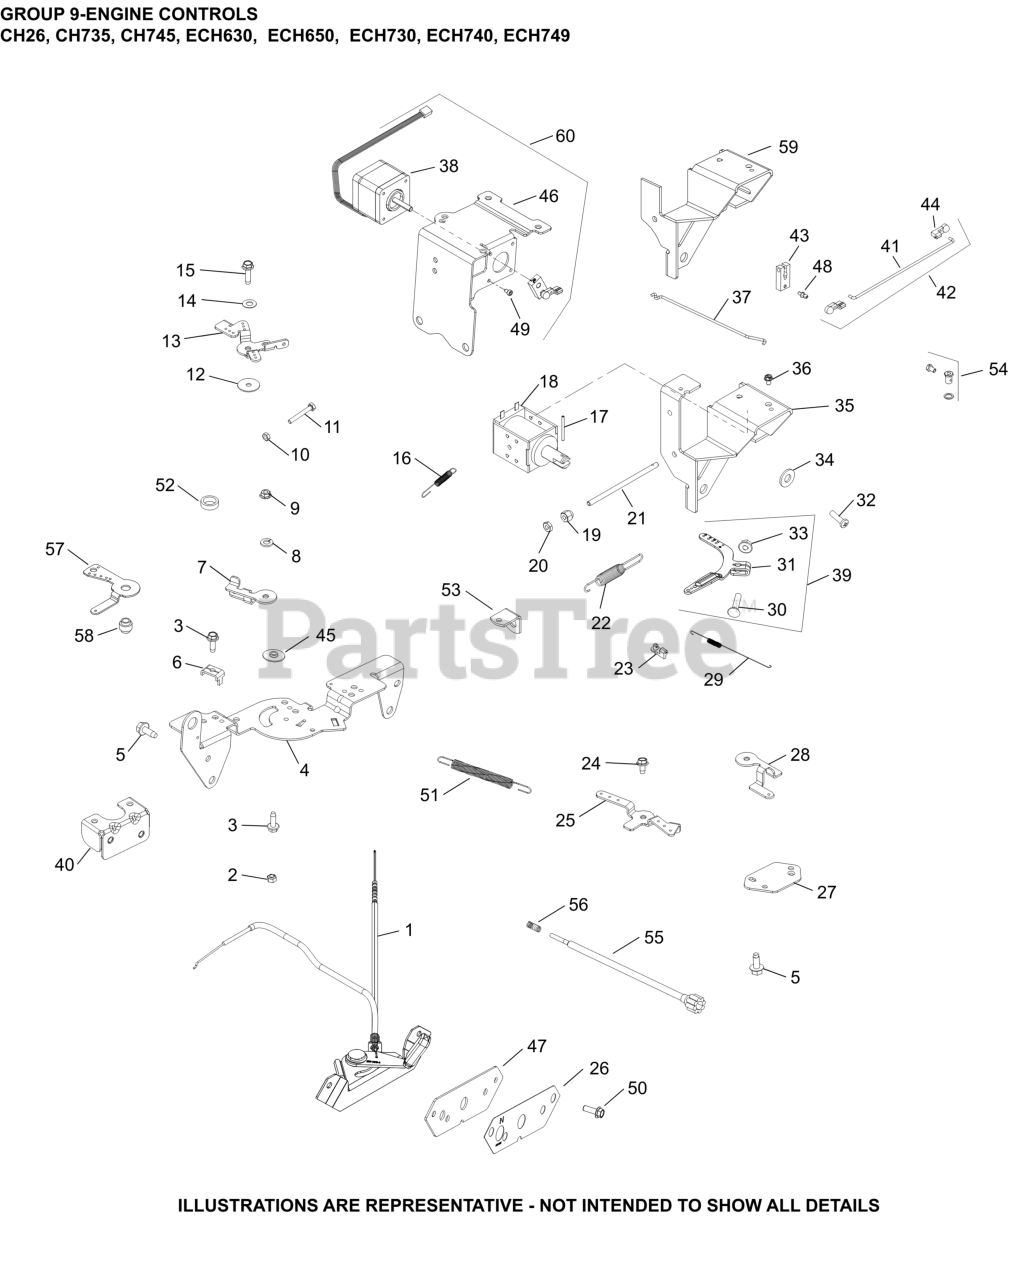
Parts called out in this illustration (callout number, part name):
5	SCREW, THREAD FORMING
18	SOLENOID, IDLE
19	NUT, ADJUSTING
20	NUT, MACH SCREW #10-32 GRD 2
21	ROD, SPEED CONTROL
22	SPRING, GOVERNOR (ORANGE)
23	BUSHING, THROTTLE LINKAGE
29	SPRING, LINKAGE
30	BOLT, RD HD SQ NECK M6X1.0X25
31	LEVER, GOVERNOR - (#2409069S)
31	LEVER, GOVERNOR
33	NUT, FLG M6X1.0
35	BRACKET, SOLENOID-(#24126275S)
36	SCREW, SLT WSH HD 8-32X1/4"
37	LINKAGE, THROTTLE
39	LEVER, GOVERNOR ASSEMBLY
55	CABLE, IDLE ADJUSTMENT
56	SPRING, SPEED CONTROL (SHORT)
